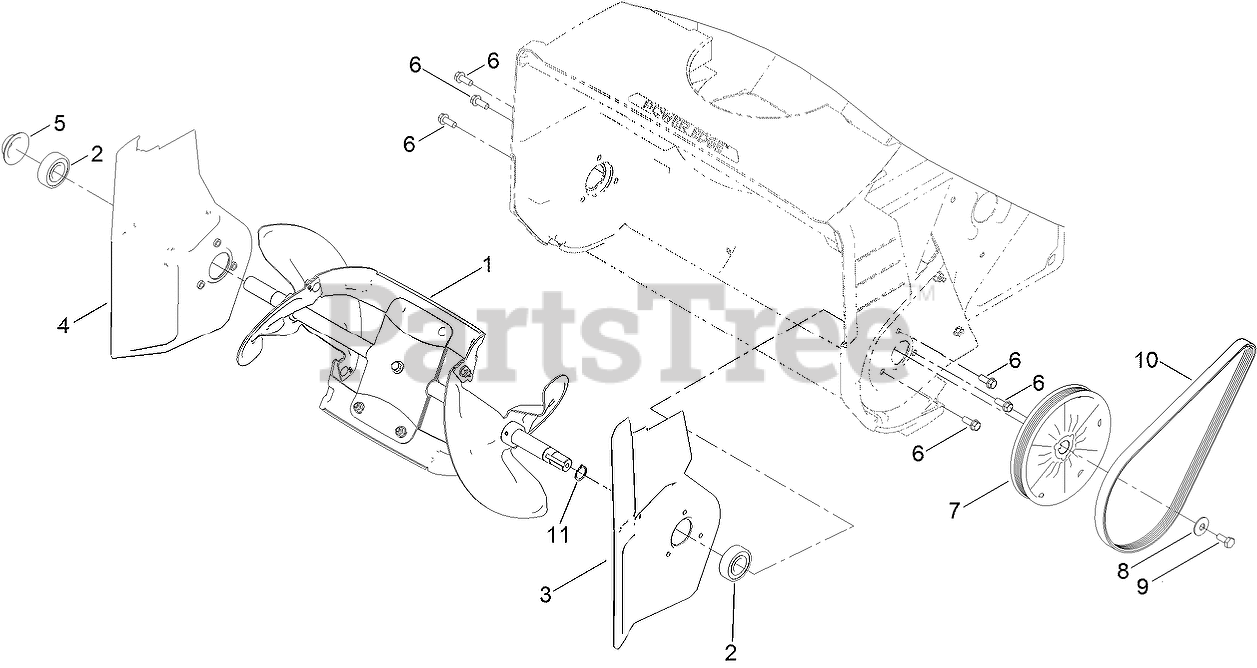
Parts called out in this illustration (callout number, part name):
1	ROTOR ASM
2	BEARING-BALL
3	EXTENSION-LH
4	EXTENSION-RH
5	CAP-SIDEPLATE, RH
6	SCREW-HWH
7	ROTOR PULLEY ASM (6 GROOVE)
8	WASHER-BELLEVILLE
9	SCREW-HH
10	BELT-V, RIBBED
11	RING-SNAP, EXTERNAL
